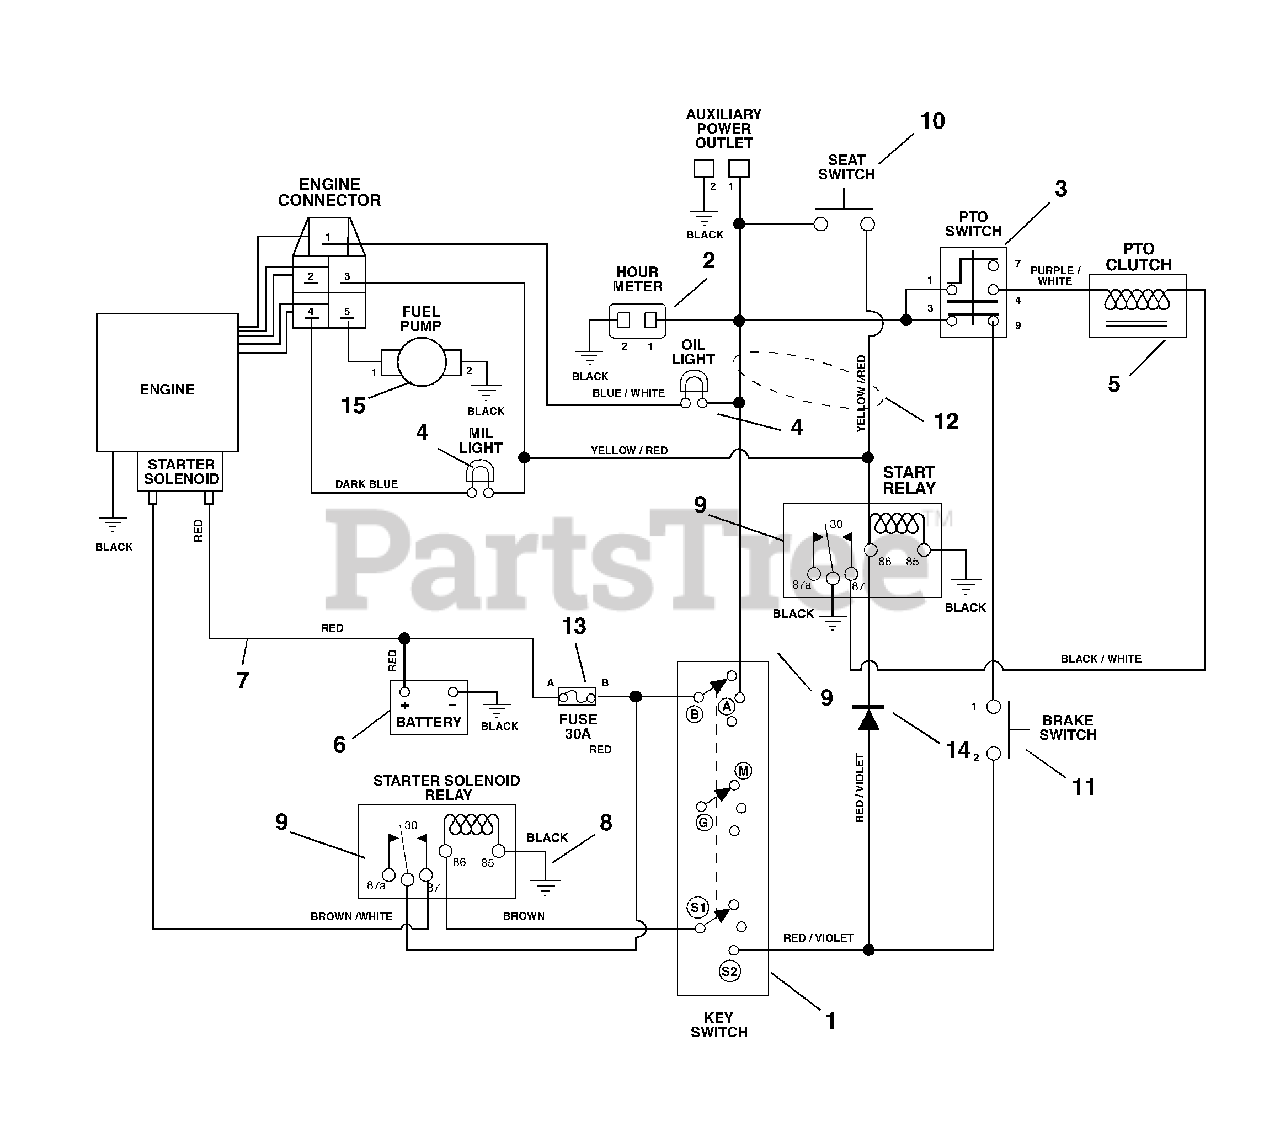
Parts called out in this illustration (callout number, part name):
1	Key Switch
2	Hour Meter
3	Switch-Clutch With Retainer Ring
4	Light-Indicator
5	Electric Clutch
6	Battery with Tube
7	Cable-Battery To Solenoid
8	Ground Cable
9	Relay
10	Seat Switch
11	Switch-Single Pole
12	Harness-Briggs Wiring
13	Fuse, 30 Amp
14	Molded Diode Plug-Black 1-Amp
15	Pump, EFI Fuel
